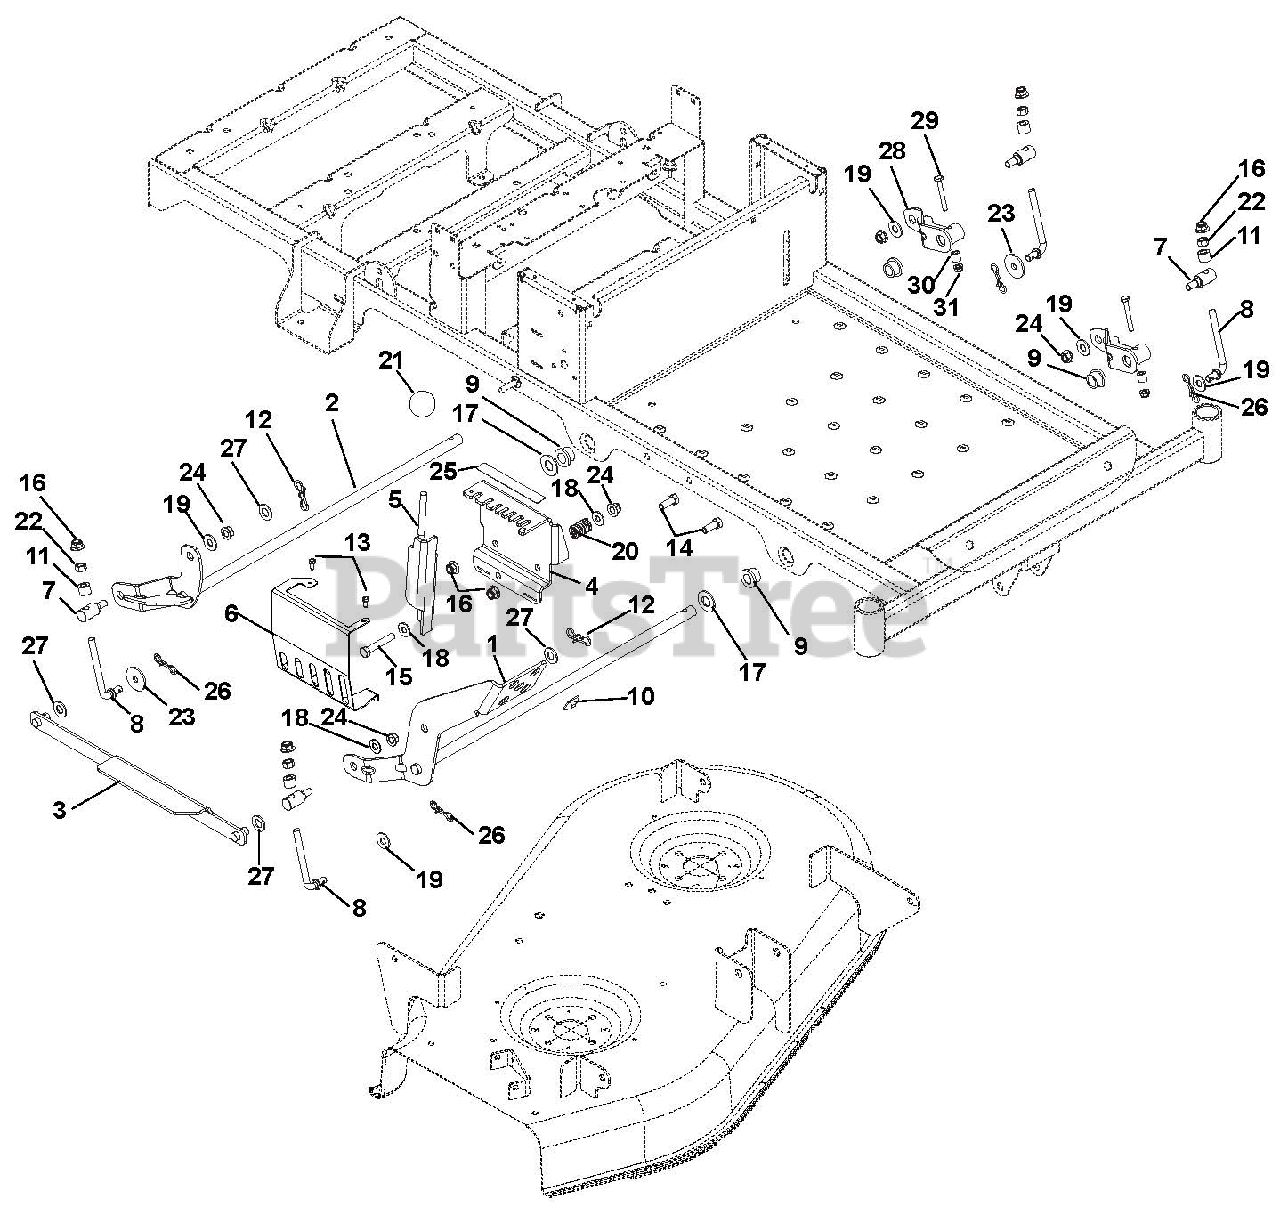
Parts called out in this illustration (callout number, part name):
1	WLDMT, FOOTPEDAL
2	WLDMT, REAR DECK LIFT
3	WMT, LIFT/HOC LINK
4	BRKT, HOC
5	WMT, HOC LEVER
6	GUARD, DECK HOC
7	TRUNNION, DECK ADJUSTER
8	WIREFORM, DECK ADJUSTMENT
9	BSHG-FLG .629X.879X.469X1.250
11	BSHG-SLV .391X.688X.52 PM
12	PIN,BOW TIE LOCKING .091X1.875
13	@SCR-TAP 10-24X.50 HWH TR YWZC
14	@BLT-HEX .38-16X1.00 GR5 YWZC
15	@BLT-HEX .38-16X2.25 GR5 YWZC
16	@NUT-LK-NYL-FLG .38-16 YWZC
17	@WSHR-FL-STL.656X1.31X.095 YWZ
18	@WSHR-FL-STL.38X.875X.083 YWZC
19	@WSHR-FL-STL.406X.812X.065 YWZ
20	SG-COMP .125X.781X1.250
21	KNOB,BALL -BLACK 1.47" .375-16
22	@NUT-HEX .38-16 YWZC
23	WSHR-FL-STL .380X1.50X.125YWZC
24	@NUT-LK-TOP-FLG .38-16 YWZC
25	DECAL, HEIGHT OF CUT
26	PIN, BOW TIE LOCKING
27	WSHR-FL-NYL .518X1.000X.080
28	WLDMT, DECK LIFT ARM
29	@BLT-HEX .25-20X2.00 GR5 YWZC
30	BSHG-SLV .265X.500X.500
31	@NUT-LK-NYL-FLG .25-20 YWZC
